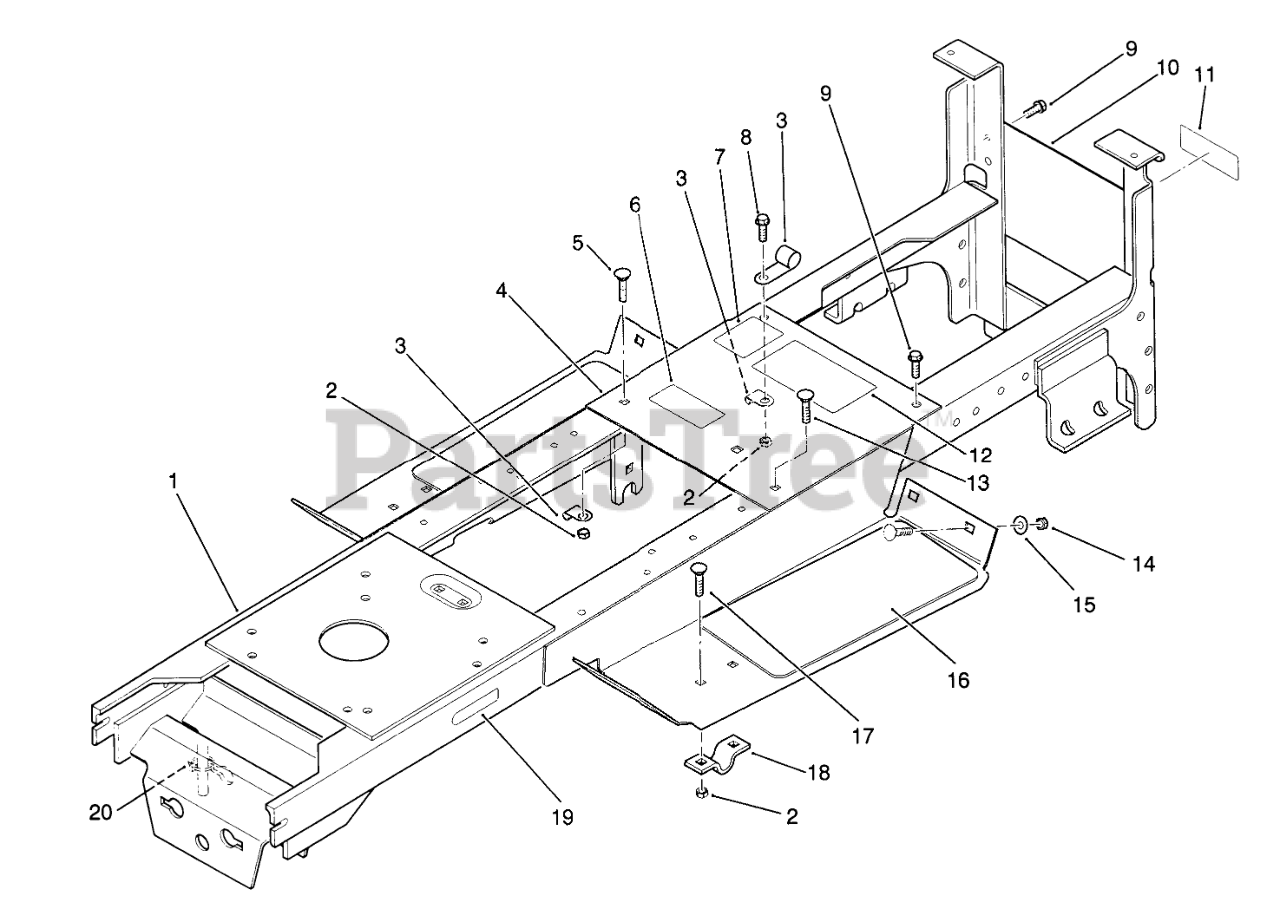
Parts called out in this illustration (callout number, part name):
1	Frame
2	Nut
3	THROTTLE CONTROL CLP
4	Panel
5	Bolt-Carriage
6	Decal-Danger
7	DECAL-PARKING BRAKE
8	Bolt
9	Screw
10	PANEL-REAR R
11	ROLLER-CHAIN #50 SEC
12	DECAL-DANGER
13	Bolt-Carriage
14	Nut
15	Washer-Lock
16	PAD FOOTREST
17	Bolt-Carriage
18	CLAMP
19	Decal-Attac-O-Matic
20	PLASTIC TIE
